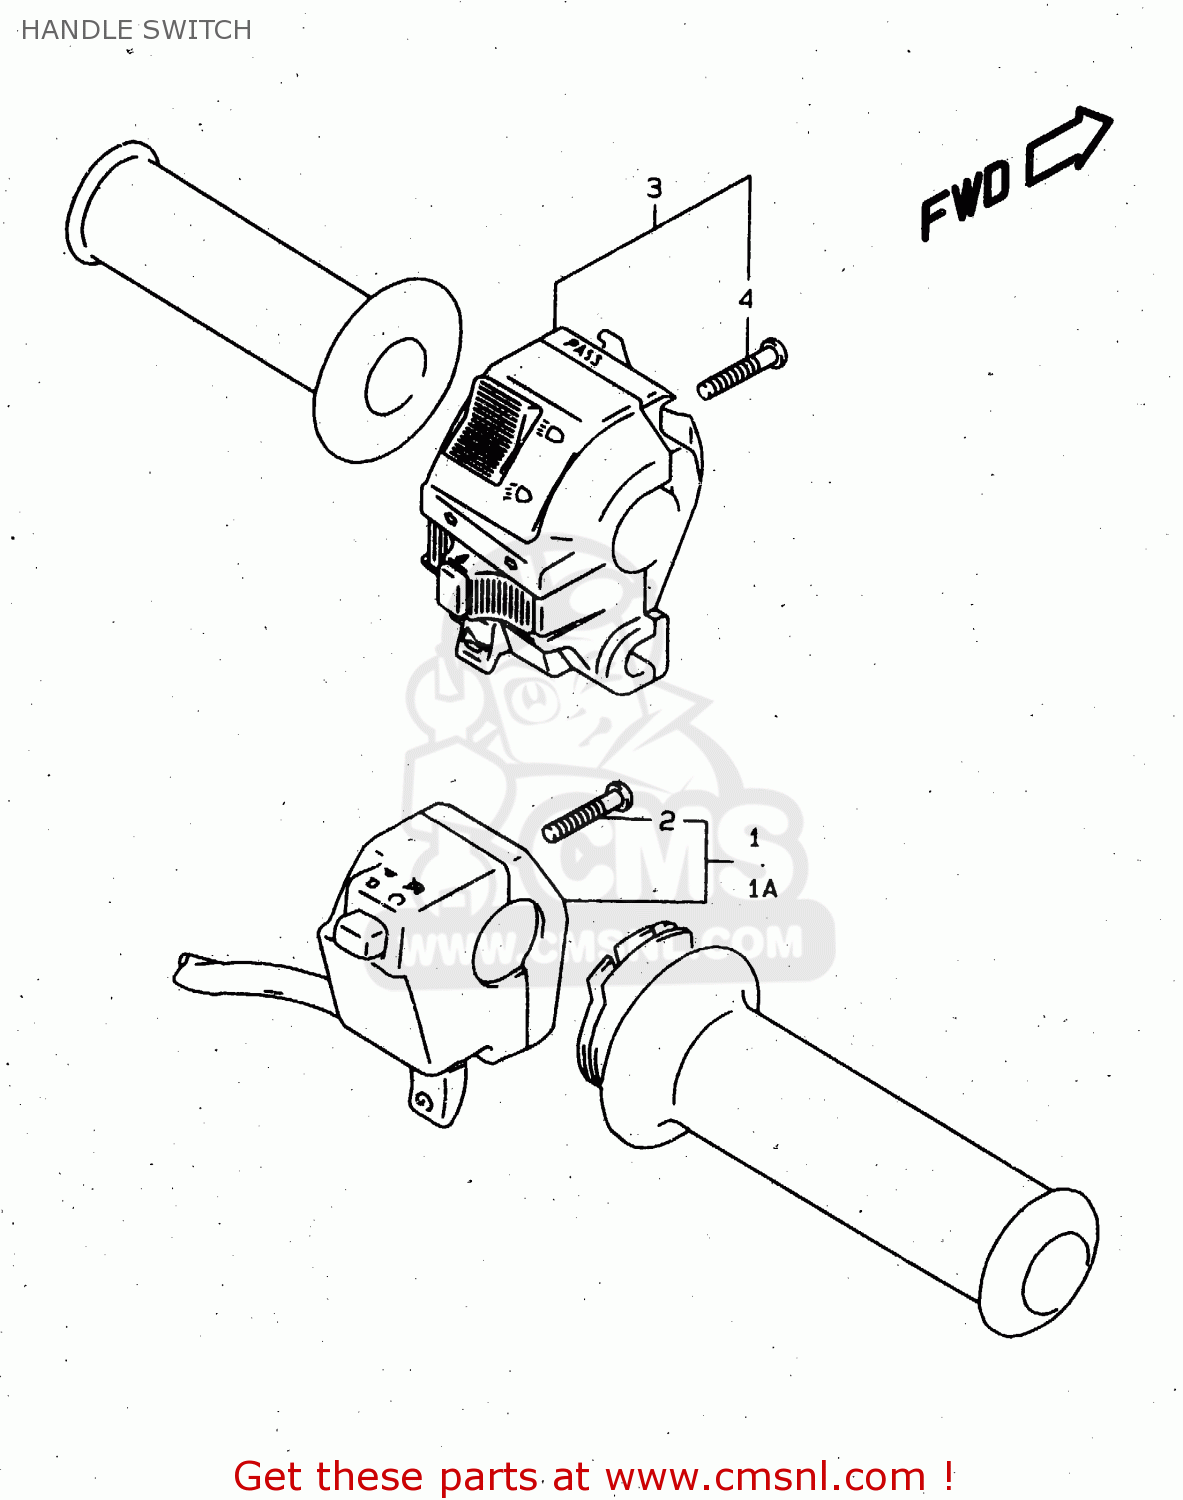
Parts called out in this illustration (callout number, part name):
1	SWITCH ASSY,HANDLE,R
1A	SWITCH ASSY,HANDLE,R
2	SCREW(5X25)
3	SWITCH ASSY,HANDLE,L
4	SCREW
